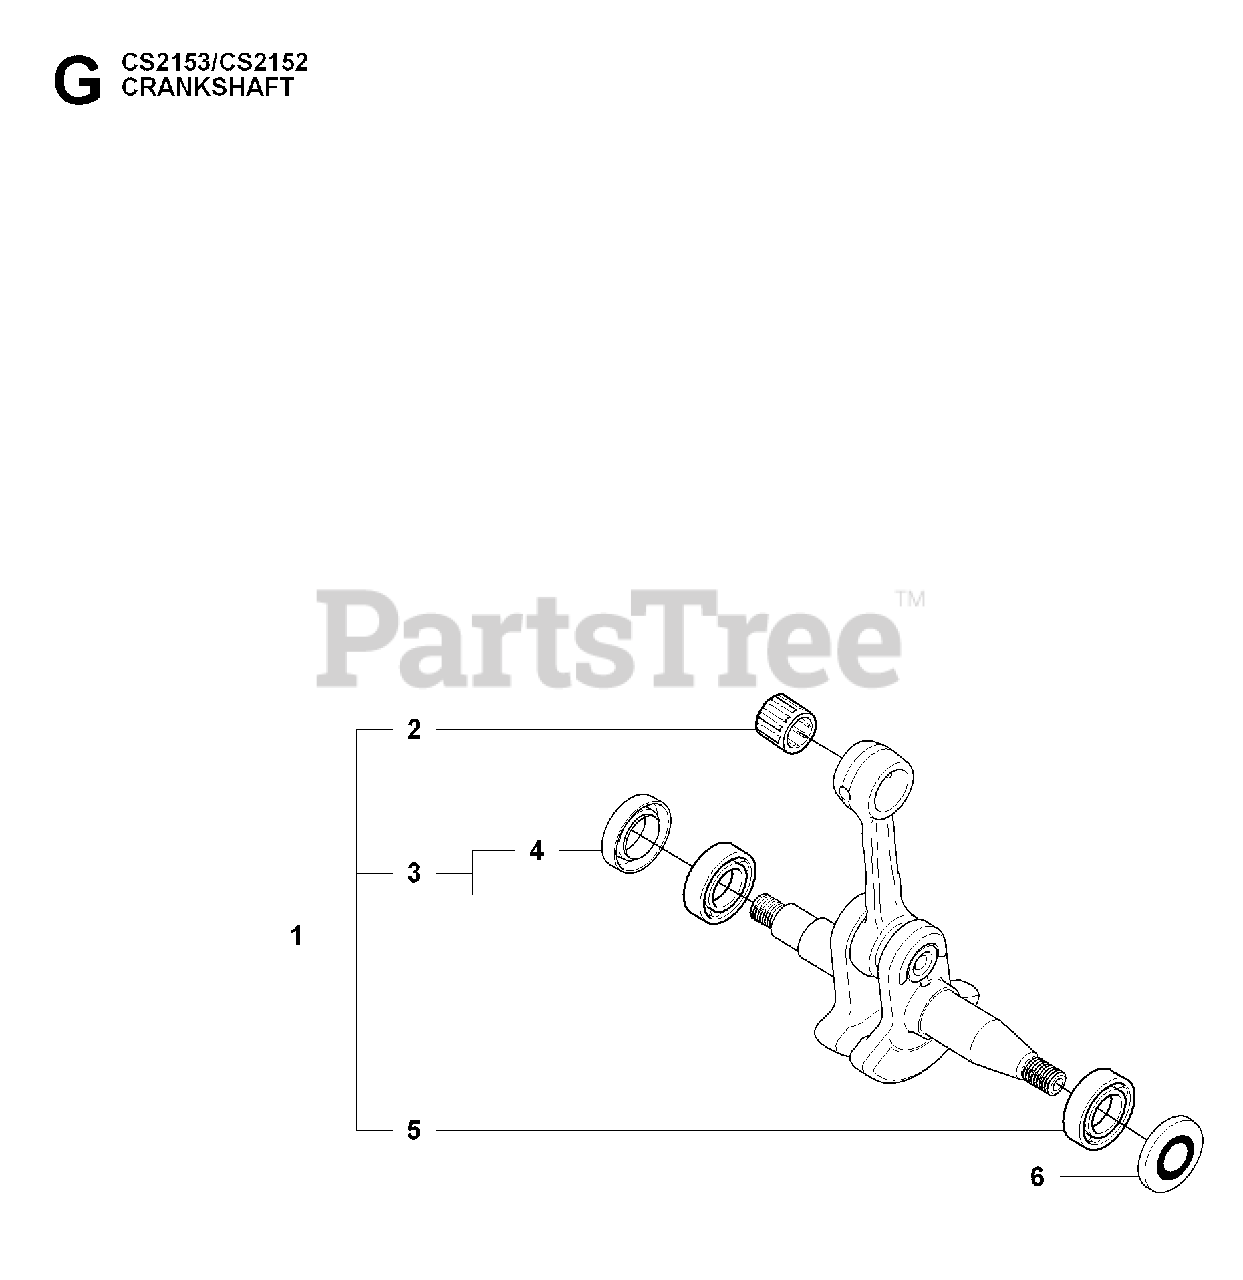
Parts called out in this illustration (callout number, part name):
1	%CRANKSHAFT
2	RP SUPPORT BUSHING
3	%BALL BEARING
4	RADIAL SEAL
5	BALL BEARING-6202-C3 SKF
6	SEAL RING
